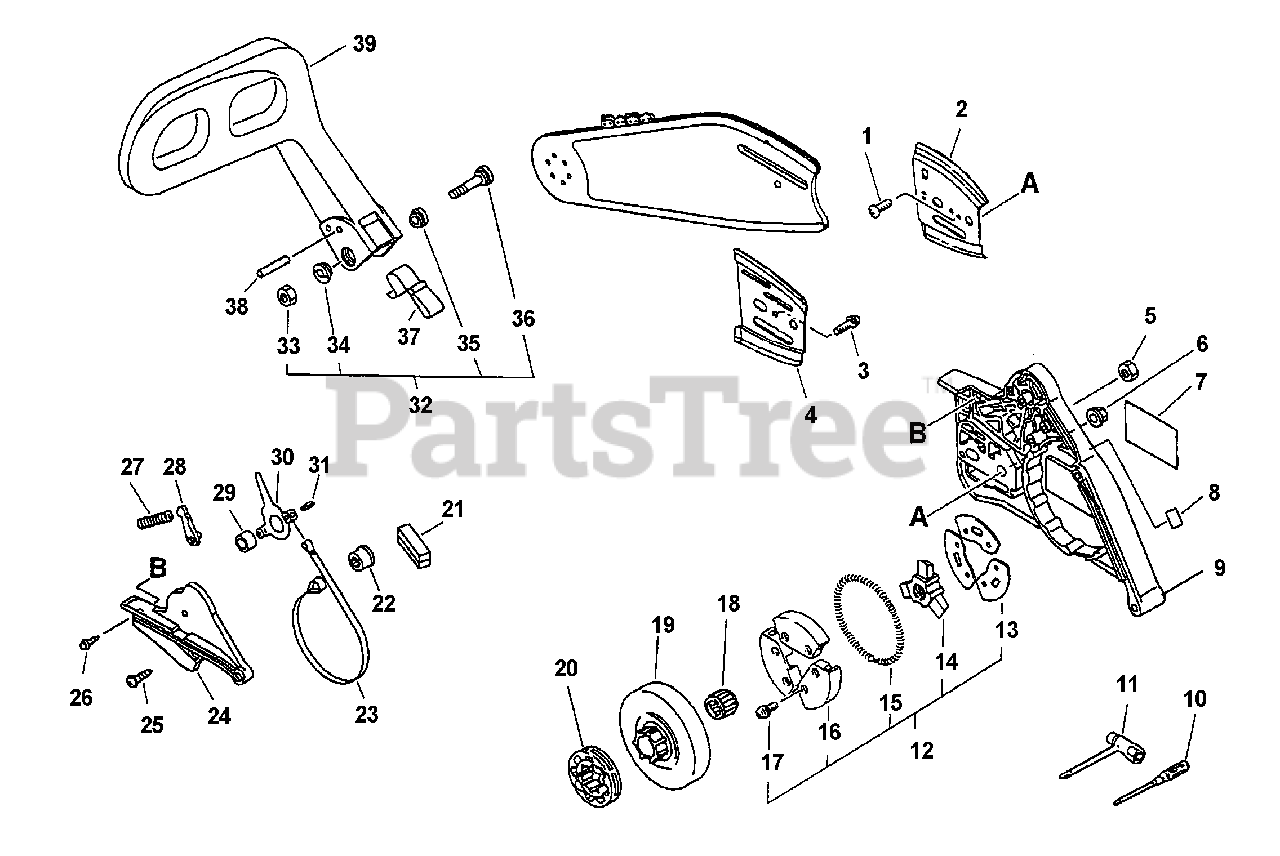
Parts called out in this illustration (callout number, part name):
1	SCREW 3×6
2	PLATE, GUIDE - OUTER
3	SCREW 4×8
4	PLATE, GUIDE - INNER
5	NUT 3 MM
6	NUT, FLANGE M8×1.25
7	LABEL, ECHO
8	LABEL, CAUTION
9	GUARD, SPROCKET
10	SCREWDRIVER, PHILLIPS
11	T-WRENCH 13×19×180
12	CLUTCH ASSY
13	PLATE, CLUTCH
14	HUB, CLUTCH
15	SPRING, CLUTCH
16	CLUTCH SHOE SET
17	BOLT 4×6
18	BEARING, NEEDLE
19	DRUM, CLUTCH
20	SPROCKET, RIM 3/8"×7T
21	SEAL, BRAKE
22	ADJUSTER, BRAKE
23	BAND, BRAKE
24	COVER, BRAKE
25	SCREW 3×18
26	SCREW 4×12
27	SPRING, BRAKE
28	STOPPER, BRAKE
29	SPACER 8×12×9
30	LEVER, BRAKE
31	PIN, SPRING 4×8.8
32	SCREW KIT
33	NUT, LOCK M5
34	COLLAR 5.3×10×13×L5
35	COLLAR 5
36	SCREW 5×35
37	SPRING, FLAT
38	PIN 3.5×26
39	LEVER, BRAKE
